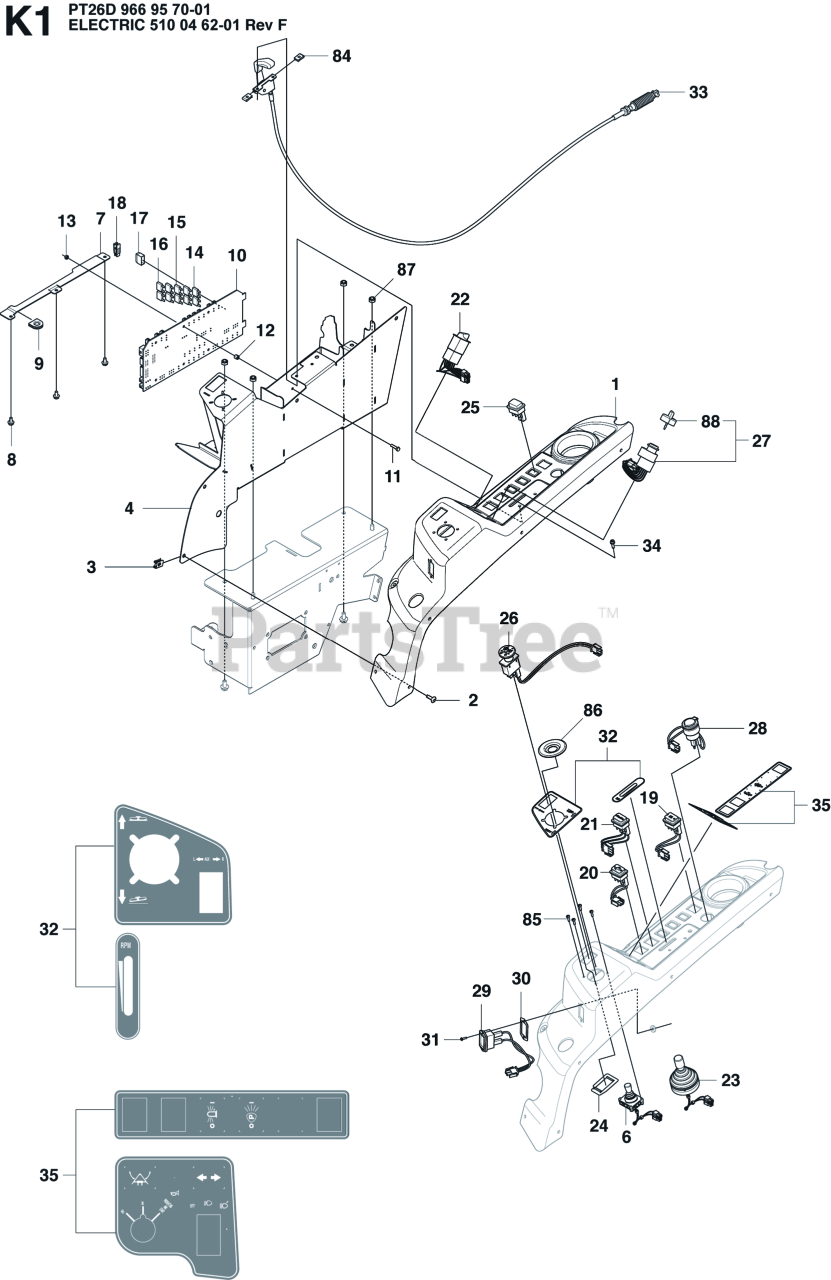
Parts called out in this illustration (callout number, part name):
8	SCREW EHHFM
11	SCREW M6S 5X20
13	LOCKNUT M5
17	COVER FUSE HOLDER
33	THROTTLE HANDLE ASSY
87	LOCKNUT M8
